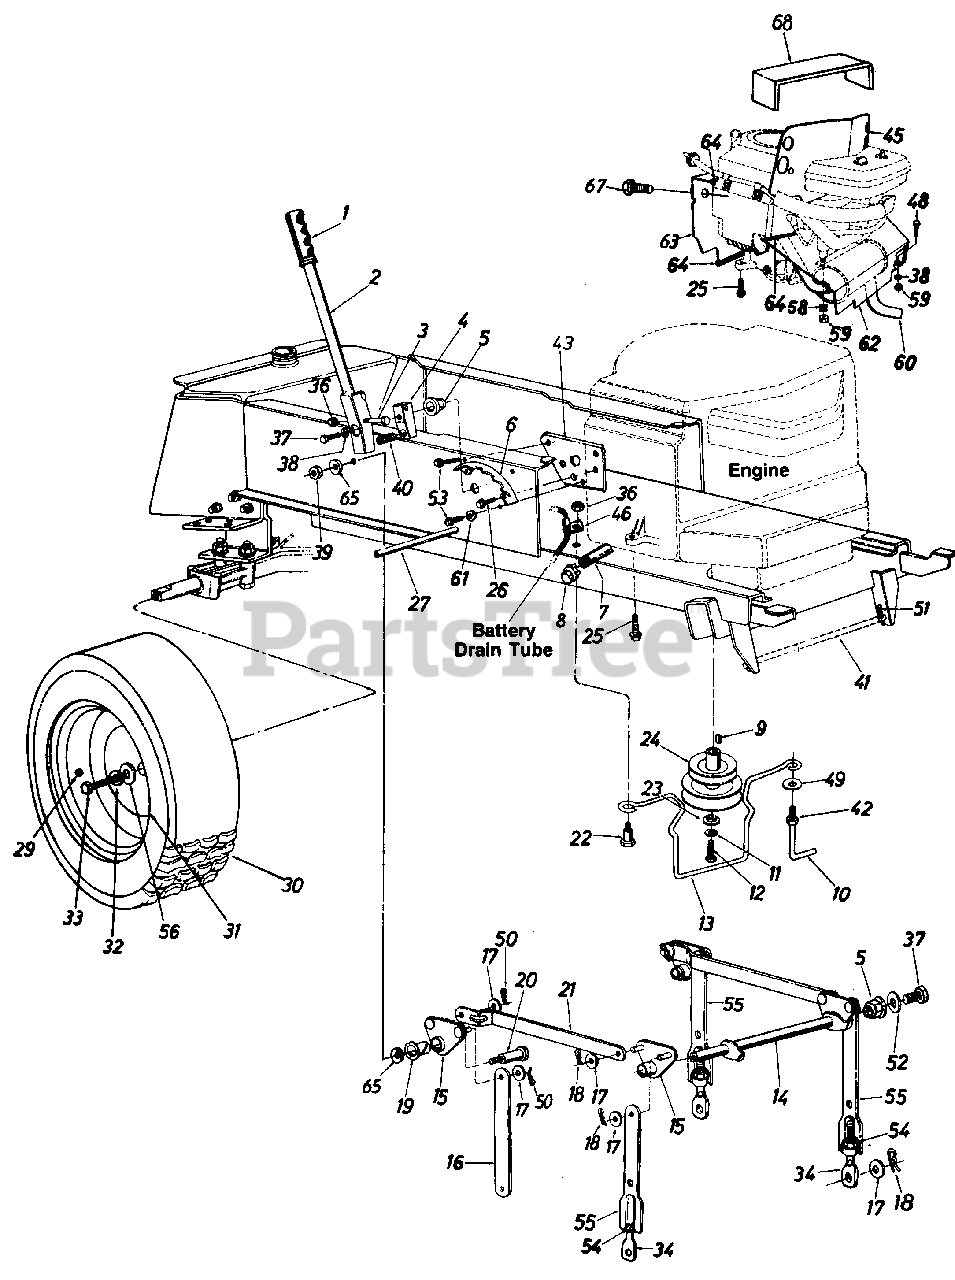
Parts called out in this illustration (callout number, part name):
1	Grip
2	Lift Handle Ass'y.
3	Hex Bolt 5/16-18 x 1.50" Lg.
4	Lift Shaft Drive
5	Plastic Hex Brg. 5/8" I.D.
8	Pipe Cap 3/8-18 Npt.
9	Sq. Key 1/4" x l.50n
10	Belt Guard Lock Pin
11	L-Wash 7/16" Scr.
12	Hex Scr. 7/16-20 x 1.50" Lg.
13	Belt Guard
14	Lift Shaft Ass'y.
15	Lift Pivot Brkt. Ass'y.
17	Fl-Wash. 112" I.D. x 1.00" O.D. x .090
18	Hairpin Cotter
19	Nyliner 5/8" I.D. x .88" Lg.
20	Shld. Scr. 5/8" Dia. x .96" Lg. 3/8-16
23	Flat Wash. 44" I.D. x 1.25" O.D. x .17
24	Two-Step Engine Pulley
25	Hex Wash. Hd. Scr. 3/8-16 x 1.25" Lg.
26	Hex Thd. Rolling Scr. 5/16-18 x .75" Lg.
27	Running Board Rod
29	Air Valve
30	Rear Wheel Ass'y. Comp.
31	Rear Wheel Rim Only
32	Bell-Wash. .345" I.D. x .88"
33	Hex Bolt 5/16-24 x .75" Lg.
34	Eye Bolt Adj. Link 1/2-13 Thd.
36	Hex Cent. L-Nut 5/16-18 Thd.
37	Hex Bolt 5/16-24 x .62" Lg.
38	L-Wash. 5/16" I.D.
39	Hex Center L-Jam Nut 3/8-16 Thd.
40	Compression Spring
41	Deck Connecting Rod
42	Hex Nut 5/16-24 Thd.
46	Mounting Clamp
48	Hex Bolt 5/16-18 x .75" Lg.
49	Bell-Wash..39" I.D.
50	Cotter Pin .09 Dia. x 1.0" Lg.
51	Int. Cotter Pin
52	Flat Wash. .34" I.D. x 1.12" O.D. x .125
53	Hex Wash. Hd. AB-Tap Scr. 5/16 x .62" Lg.
54	Hex Nut 1/2-13 Thd.
56	Fl-Wash. .34" I.D. x 2.0n O.D.
58	Spec. L-Wash. 5/16" I.D.
59	Hex Nut 5/16-18 Thd.
60	Muffler
61	Flat Wash. 344" I.D.
62	Front Heat Shield
63	Rear Heat Shield
64	Trim Strip 10" Lg.
65	Bell-Wash. .40" I.D. x 1.13"
67	Hex Wash. TT-Tap Scr. 1/4-20 x .5" Lg.
68	Foam
